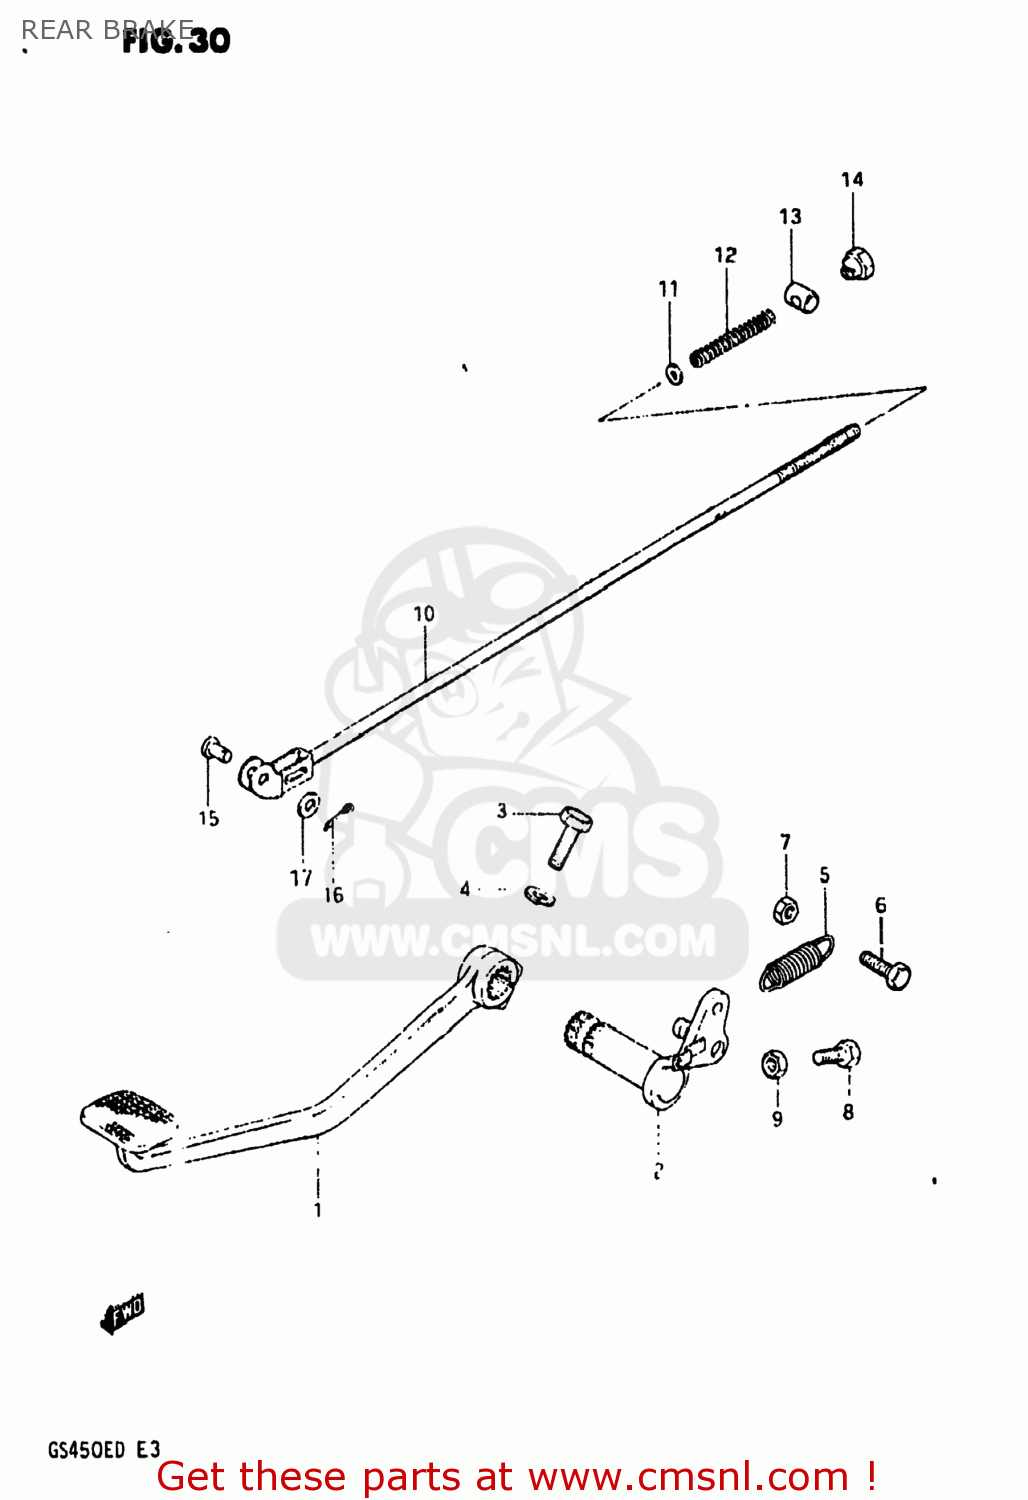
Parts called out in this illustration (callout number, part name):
1	PEDAL,BRAKE
2	ARM,BRAKE PEDAL
3	BOLT
4	LOCK WASHER
5	SPRING
6	BOLT
7	NUT
8	BOLT
9	NUT
10	ROD ASSY,RR BRAKE
11	WASHER
12	SPRING
13	PIN
14	NUT
15	PIN(L:13.5)
16	PIN 20X20
17	WASHER
